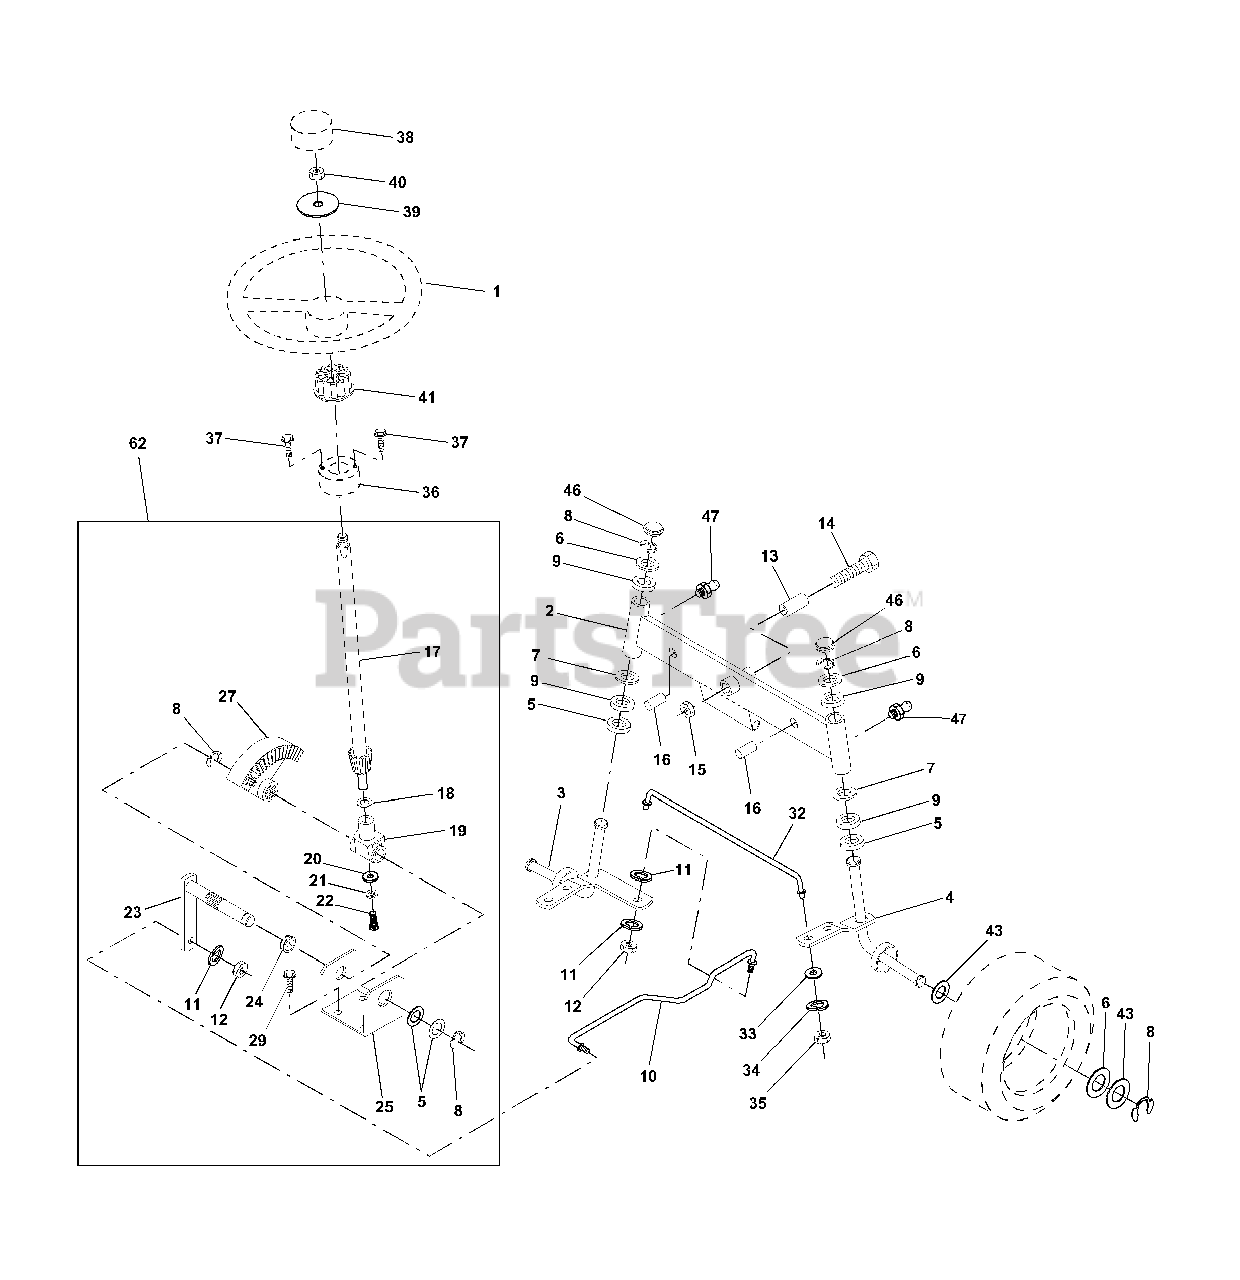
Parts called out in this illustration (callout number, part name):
1	Wheel Steering Auto Grey
2	Axle Asm Fr LT W/gzks 38/42
3	Spindle Asm LH
4	Spindle Asm RH
5	Bearing Race Thrust Harden
6	Washer 25/32 X 1-5/8 X 16 Ga
7	Washer 27/32 X 1-1/4 X 16 Ga
8	Ring Klip #t5304-75
9	Bearing Col Strg Blk
10	Link Drag Sol Ball Jt 20 064
11	Washer Lock Hvy Hlcl Spr 3/8
12	Nut Fin Hex 3/8-24 Unf
13	Spacer Bearing Axle Front
14	Bolt Hex 5/8-11 Unc X 3-1/2
15	Nut Lock Flange 5/8-11 Unc
16	Pin Axle 5/8 X 1 55/1 54 Lg
17	Shaft Asm Strg 20 31 x 3/4 YP YT
18	Washer Thrust 515x 750x 033
19	Support Shaft
20	Washer Shim 1/4 X 5/8 X 062
21	Washer Lock Hvy Helical 1/4
22	Screw Hex Socket 1/4-20 X 5/8
23	Shaft Asm Pittman
24	Nyliner Snap In
25	Bracket Steering
27	Gear Sector
29	Screw Thdrol 3/8-16x3/4 Ty-tt
32	Rod Tie Wire Form 19 75 Elec
33	Washer 11/32 x 3/4 x 16 Ga.
34	Washer, Lock Hvy Hlcl Spr 5/16
35	Locknut 5/16-24 Unf
36	Bushing Strg
37	Screw Slftp #10-24 X 1/2 TT-B
38	Insert Cap Strg Wh Aut Hus Gry
39	Washer 53 X 2 25 X 160 Zinc
40	Nut Hex Jam Toplock 1/2-20 Unf
41	Adapter Wheel Strg 758/ 753id
43	Washer 25/32 X 1 1/4 X 16 Ga
46	Cap Spindle Fr Top Blk
47	Fitting Grease
62	Steering Assembly
